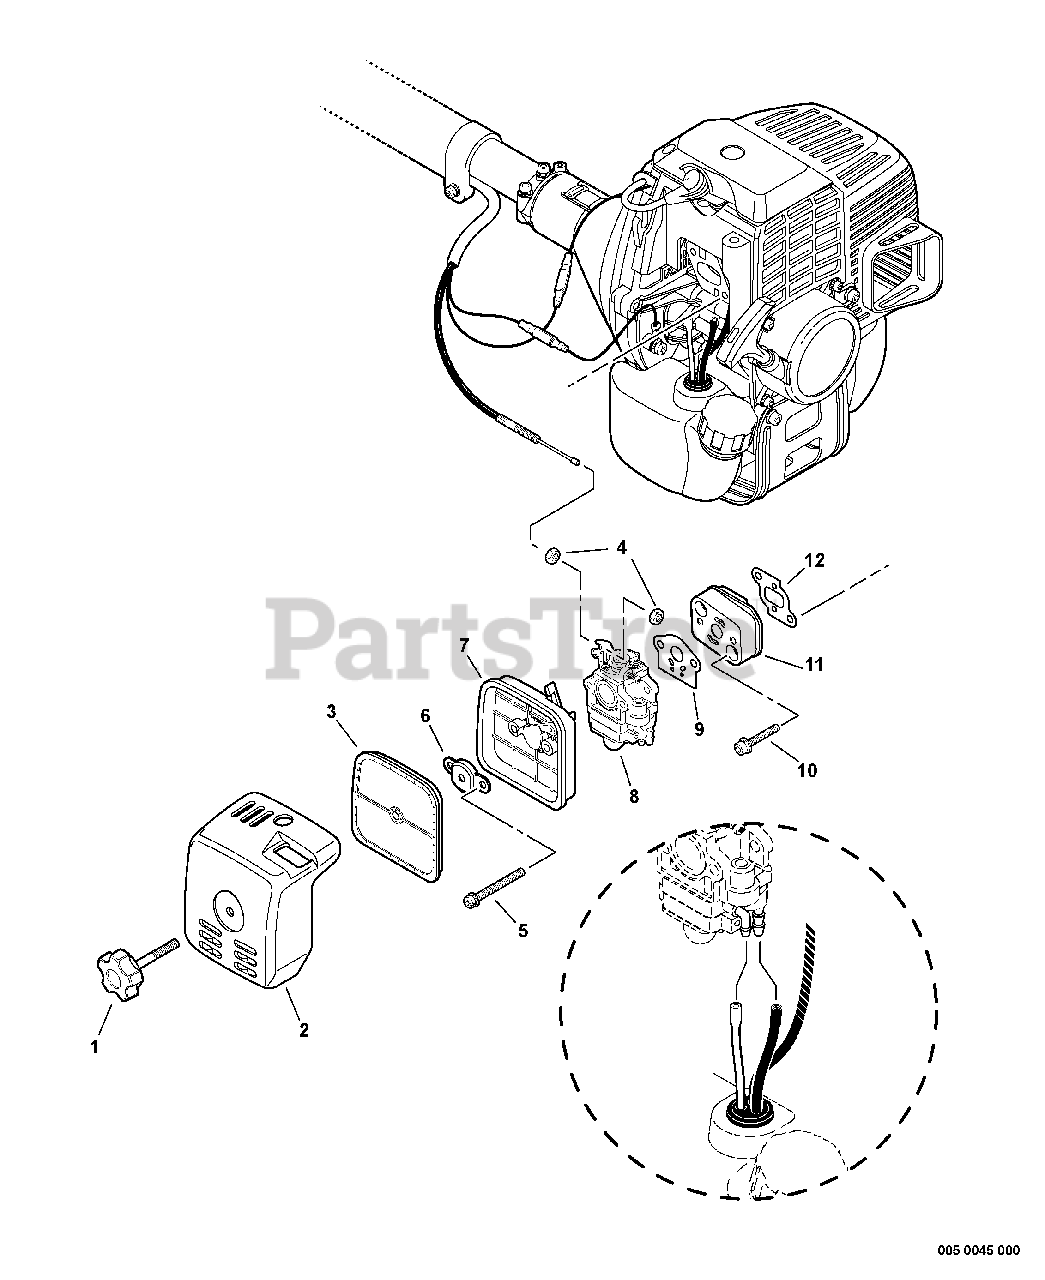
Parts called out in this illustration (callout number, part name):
1	THUMBSCREW
2	COVER, AIR FILTER
3	FILTER, AIR - HEAVY DUTY
5	SCREW - 5X60
6	PLATE, PREVENT
7	CASE, AIR FILTER
8	CARBURETOR
9	GASKET, INTAKE
10	SCREW - 5X25
11	INSULATOR, INTAKE
12	GASKET, INTAKE
